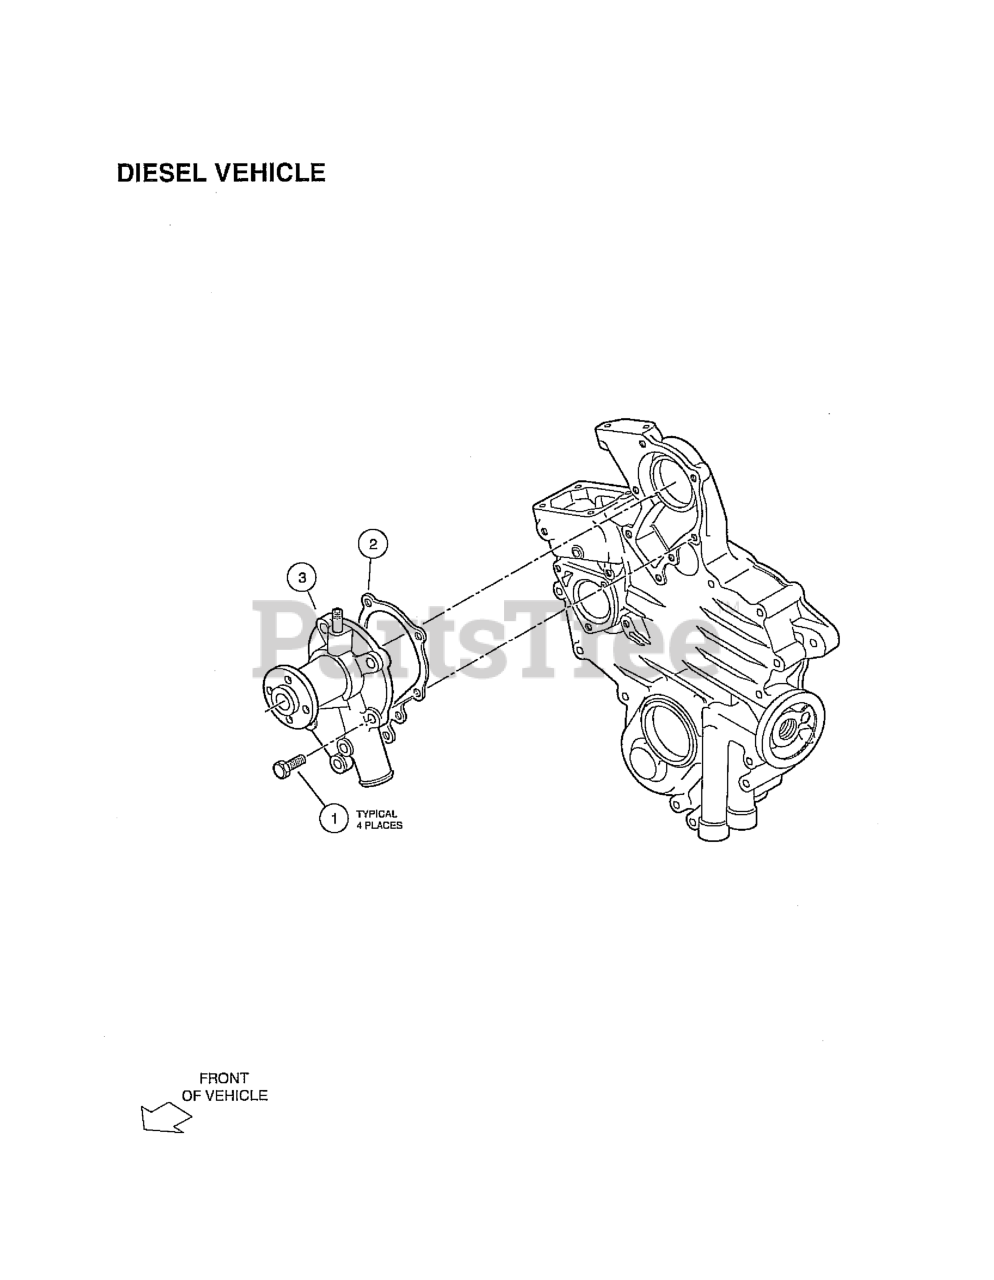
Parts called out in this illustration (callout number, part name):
1	BOLT, M6 X 1 X 22
2	GASKET, WATER PUMP, D722
3	WATER PUMP ASSEMBLY
